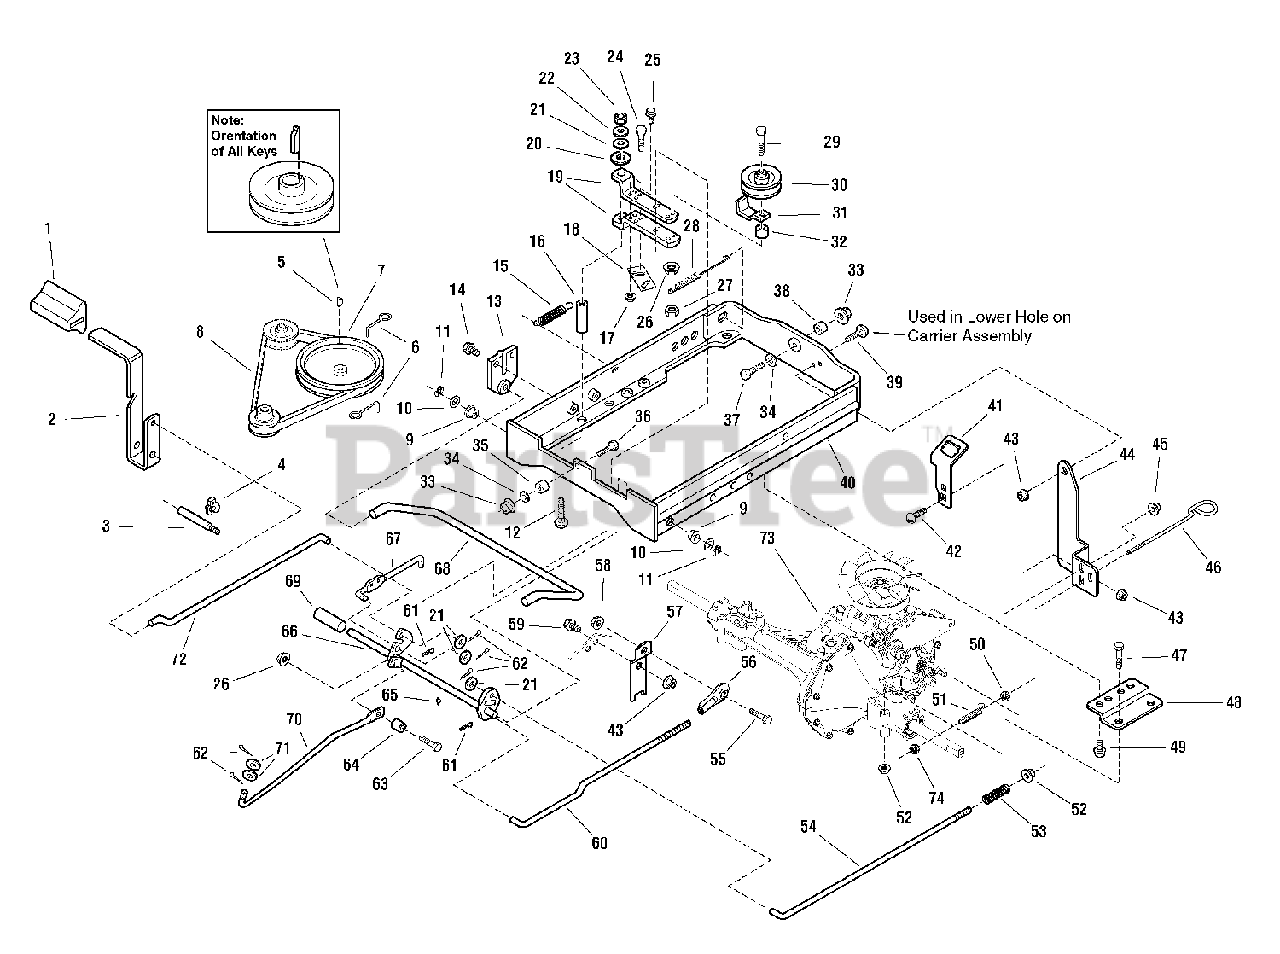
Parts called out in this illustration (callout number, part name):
1	PAD, Brake
2	LEVER, Clutch
3	PIVOT, Brake
4	RING, Klipring Extension
5	KEY, Hi-Pro
6	STOP, Belt
7	PULLEY & HUB ASSEMBLY, Engine
8	V - BELT (4L 42.0 ET KEV)
9	BUSHING
10	WASHER, 1/2
11	RING, Klipring Extension
12	CARRIAGE BOLT, 5/16 - 18 x 2-1/4 G5
13	BRACKET, Torsion Bar
14	SCREW, Hex, Washer Head, Taptite, 5/16 - 18 x 1/2
15	SPRING, Extension
16	SPACER
17	NUT, Hex, Flange, 1/4 - 20, Whiz Lock LG
18	PLATE, Idler 10GA
19	CLEVIS HALF
20	WASHER, 5/8
21	WASHER, 5/16
22	LOCKWASHER, Spring 5/16
23	NUT, Hex 5/16 - 18
24	CAPSCREW, Hex Head, 1/4 - 20 x 3/4 G5
25	SCREW, Hex, Washer Head, Taptite, 1/4 - 20 x 5/8
26	NUT, Hex Flange,, 3/8 - 16 Whiz Lock LG
27	NUT, Hex, Toplock, Jam, 3/8 - 16
28	SPRING, Extension
29	CAPSCREW, Hex Head, 3/8 - 16 x 3-1/4 G5
30	PULLEY
31	GUARD, Spring
32	SPACER
33	NUT, Hex Flange, 1/2 - 13, Two-Way Lock
34	WASHER, 1/2
35	SPACER
36	CAPSCREW, Hex Head, 1/2 - 20 x 1-1/4 G5
37	CAPSCREW, Hex Head, 1/2 - 13 x 1 G5
38	SPACER
39	CARRIAGE BOLT, 5/16 - 18 x 5/8 G5
40	CARRIER ASSEMBLY
41	BRACKET, Switch Mounting (No-Mow Models Only)
42	CARRIAGE BOLT, 1/4 - 20 x 3/4 G5 (No-Mow Models Only)
43	NUT, Hex Flange, 5/16 - 18, Whiz Lock Small
44	STRAP, Torque (No-Mow Models Only)
44	STRAP, Torque
45	NUT, Hex Flange, 1/4 - 20 ESNA (No-Mow Models Only)
46	ROD
47	CAPSCREW, Hex Head, 5/16 - 18 x 2-1/2 G5
48	BRACKET, Mounting
49	SCREW, Hex, Washer Head, Taptite, 5/16 - 18 x 3/4
50	NUT, Hex Lock #10F BZ
51	SPRING, Extension
52	NUT, Hex Flange, 5/16 - 18, Two-Way Lock
53	SPRING
54	ROD, Brake
55	CAPSCREW, Hex Head, 3/8 - 16 x 1 G5
56	ROD, End
57	LEVER, Control
58	NUT, Hex Flange, 3/8 - 16, Two-Way Lock
59	CAPSCREW, Hex Head, 5/16 - 18 x 5/8 G5
60	ROD, Control
61	PIN, Quick
62	PIN, Cotter
63	SCREW, Hex, Whiz Lock, Flange, 3/8 - 16 x 1-3/4
64	SPACER
65	FITTING, Lube, 1/4 Drive
66	SHAFT & ARMS ASSEMBLY, Pivot
67	CLUTCH, Rear
68	BAR, Torsion
69	TUBE
70	ROD, Shift, Front
71	WASHER, 1/2
72	ROD, Clutch, Front
73	TRANSMISSION ASSEMBLY, Hydro Gear
74	NUT, Hex #10-24 NC-2B
